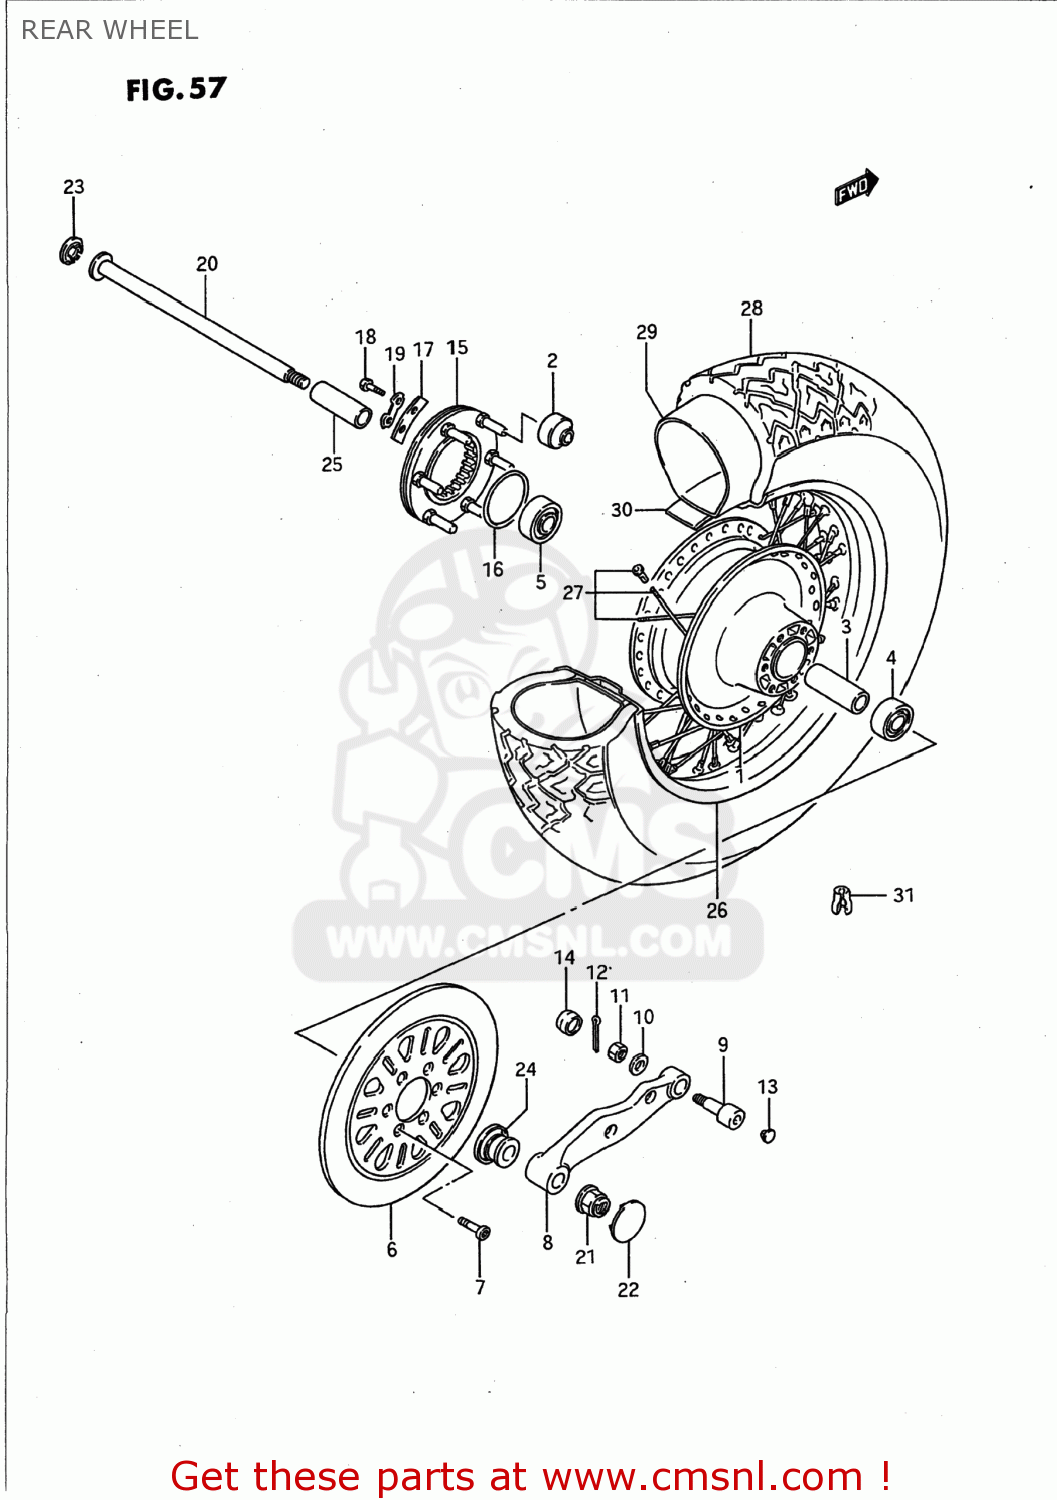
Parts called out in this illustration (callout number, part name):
1	HUB SET,RR
2	BUSH
3	SPACER(17.5X25X113)
4	BEARING
5	BEARING
6	DISC,RR BRAKE
7	BOLT
8	BRACKET,RR CALIPER
9	PIN,CALIPER BRACKET
10	WASHER(12.5X24X2.6)
11	NUT
12	PIN 20X20
13	CAP(OD:12)
14	CAP
15	JOINT ASSY,RR HUB DRIVEN
16	O RING(D:2.1,ID:65)
17	WASHER,THRUST(T:1.6)
18	BOLT(6X16)
19	WASHER
20	AXLE,RR
21	NUT
22	CAP,RR AXLE,R
23	CAP,RR AXLE,L
24	SPACER,RR AXLE,R
25	SPACER(17.3X25X79.5)
26	RIM,REAR WHEEL (MT4.00X
27	SPOKE SET,RR WHEEL
28	TIRE,RR(170/80 15M/C 77H)
29	TUBE ASSEMBLY,WHEEL,INNER
30	PROTECTOR,WHL INR TUBE
31	BALANCER,WHEEL
